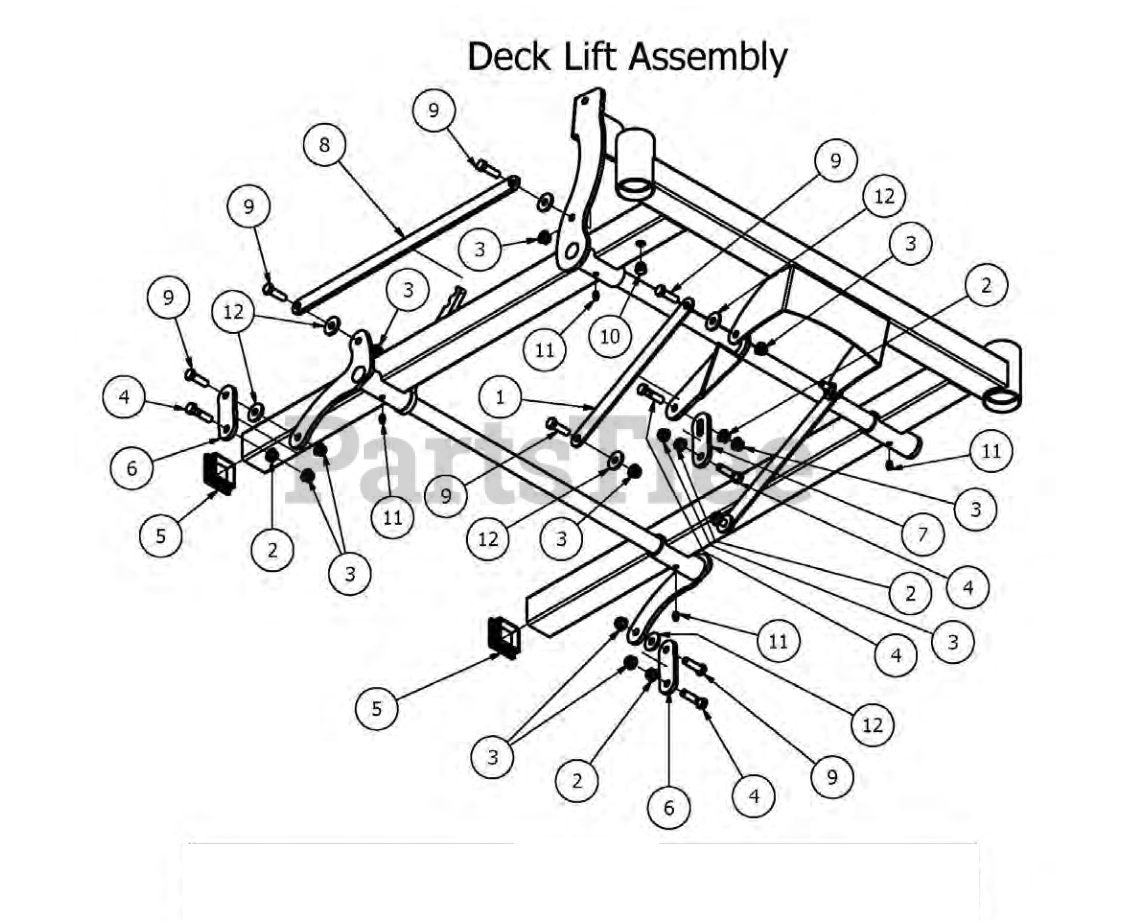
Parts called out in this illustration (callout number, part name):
1	MZ Front Arms
2	3/8" Flange Nut
3	3/8" Nylock Flange Nut
4	3/8" x 1 1/2" Hex Bolt
5	2x2 Square Plug
6	Deck Spacer (Rear)
7	Deck Spacer (Front)
8	Deck Linkage Rod
9	3/8" x 1 1/4" Hex Bolt
10	5/8 Round Insert
11	1/4" Press in Grease Fitting
12	.390 ID Plastic Washer
